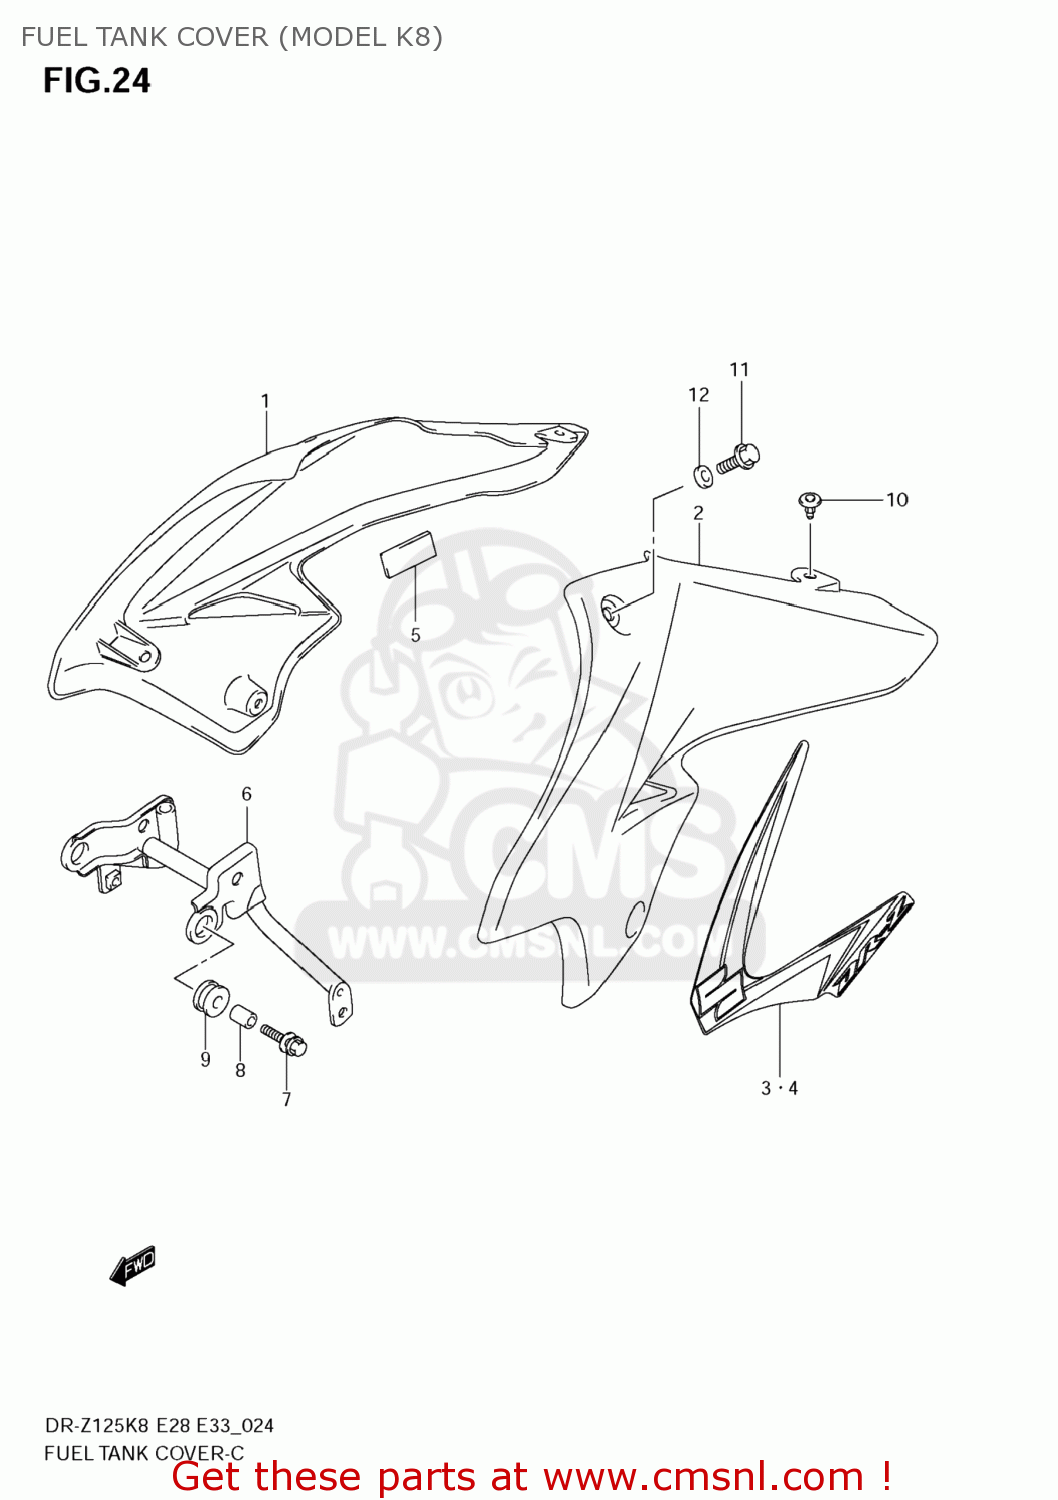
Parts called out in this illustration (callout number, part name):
1	COVER,FUEL TANK,R
2	COVER,FUEL TANK,L
3	TAPE,FUEL TANK COVER,R
4	TAPE,FUEL TANK COVER,L
5	CUSHION,FUEL TANK COVER
6	BRACKET,FUEL TANK FR
7	BOLT(6X25)
8	SPACER(6.5X9X13.5)
9	CUSHION,FUEL TANK SIDE
10	CLIP(BLACK)
11	BOLT
12	WASHER
